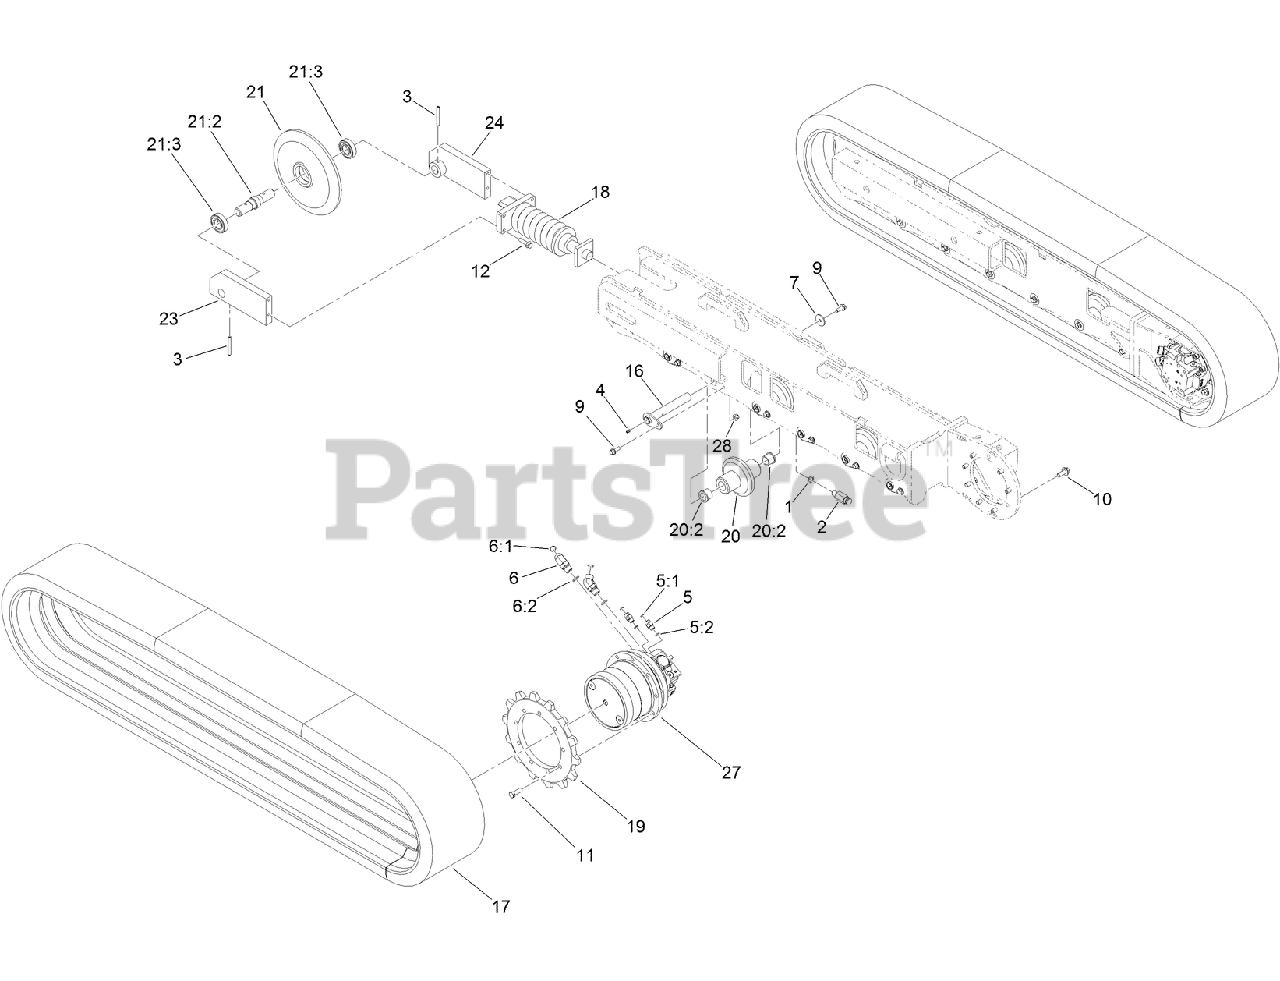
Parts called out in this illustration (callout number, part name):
1	SEAL-O RING
2	VALVE-GREASE
3	PIN-SPRING
4	FITTING-GREASE
5	FITTING-STRAIGHT
5:1	O-RING
5:2	O-RING
6	FITTING-HYD, 45 DEG
6:1	O-RING
6:2	O-RING
7	WASHER
9	SCREW-HHF
10	SCREW-HHF
11	SCREW-HH
12	SCREW-HHF
16	PIN-FLAG ASM
17	TRACK-RUBBER
18	TENSIONER-TRACK, SPRING/GREASE
19	SPROCKET-DRIVE, TRACK
20	IDLER ASM
20:2	BEARING-PLAIN, FLANGED
21	IDLER ASM
21:2	PIN-MOUNT, IDLER
21:3	BEARING-BALL
23	BRACKET-IDLER, RIGHT
24	BRACKET-IDLER, LEFT
27	PLANETARY GEARBOX ASM
28	NUT-HF, NI
